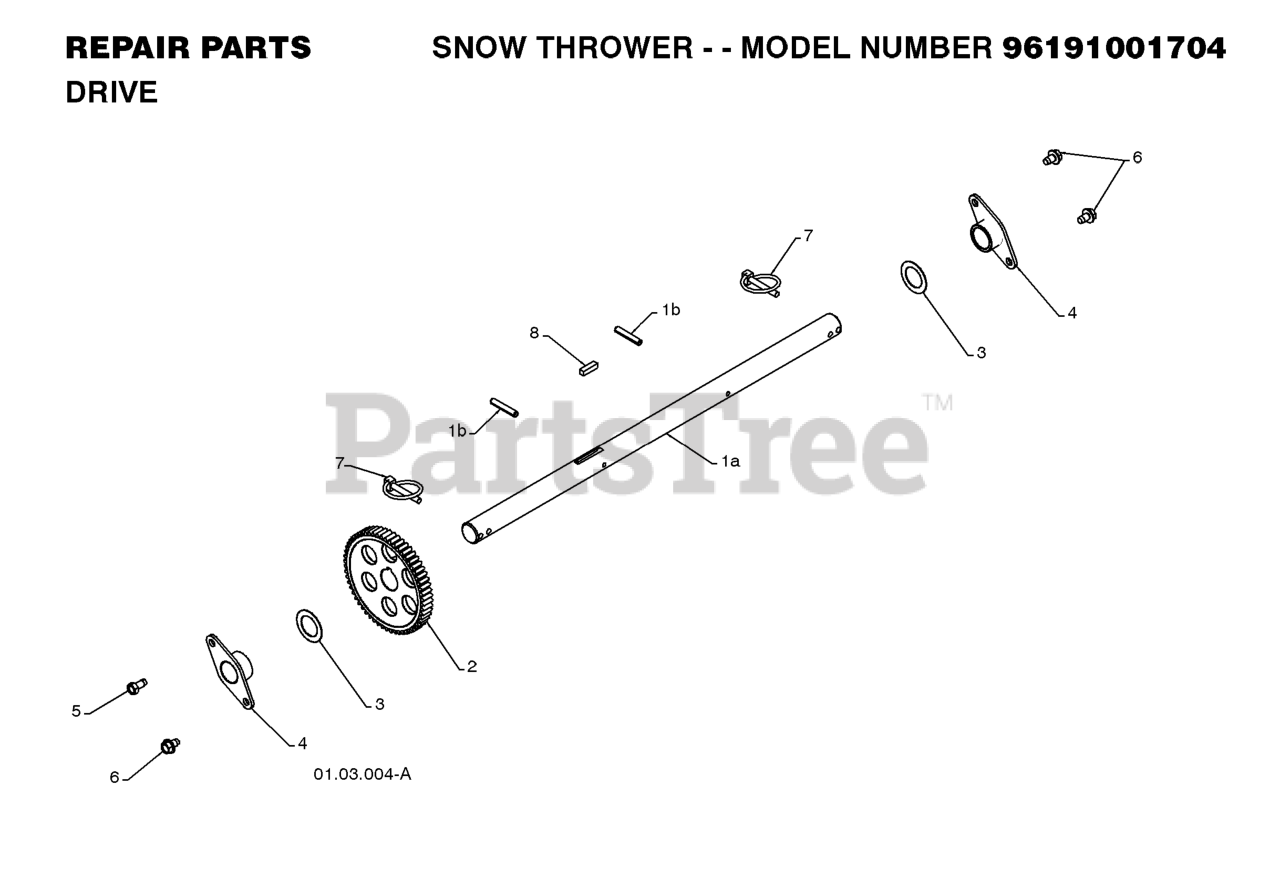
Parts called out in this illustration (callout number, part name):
1	AXLE.SHAFT.ASM.W/ROLPIN.NON-PS
1A	SHAFT.AXLE.16".SNOW
1B	PIN.ROLL.3/16
2	GEAR, AXLE (58T)
3	WASHER TRUST 1"
4	BEARING, AXLE
5	Screw 5/16-18 x 1/2 Hex, Self Tapping 5/16-18 x 1/2
6	PIN KLIK, 1/4
7	KEY, SQUARE 1/4 X .875
